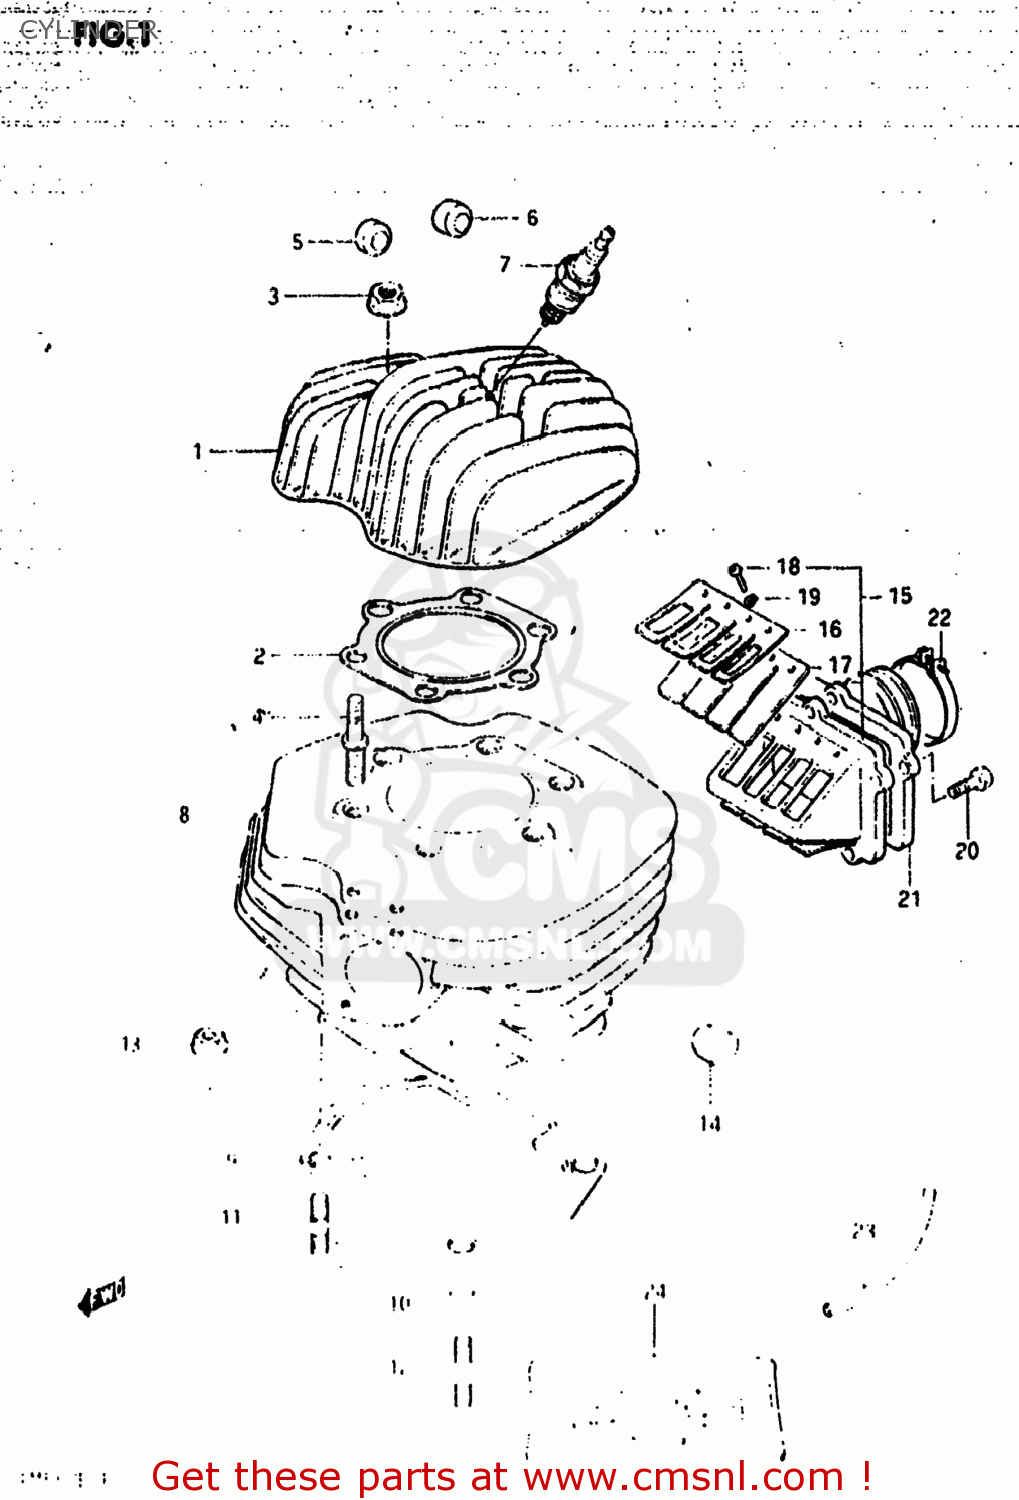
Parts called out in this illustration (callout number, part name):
1	HEAD,CYLINDER
2	GASKET,CYLINDER HEAD (NAS)
3	NUT 8MM
4	STUD
5	PAD,CYLINDER
6	PAD,CYLINDER HEAD
7	PLUG,SPARK(NGK B-8EN)
8	CYLINDER
9	GASKET,CYLINDER (MCA)
10	PIN
11	STUD
12	STUD BOLT
13	NUT
14	PAD,CYLINDER HEAD
15	VALVE ASSEMBLY,REED
16	STOPPER,REED VALVE
17	VALVE,REED
18	SCREW
19	LOCK WASHER
20	BOLT
21	PIPE,INTAKE
22	CLAMP
23	HOSE
24	GASKET
